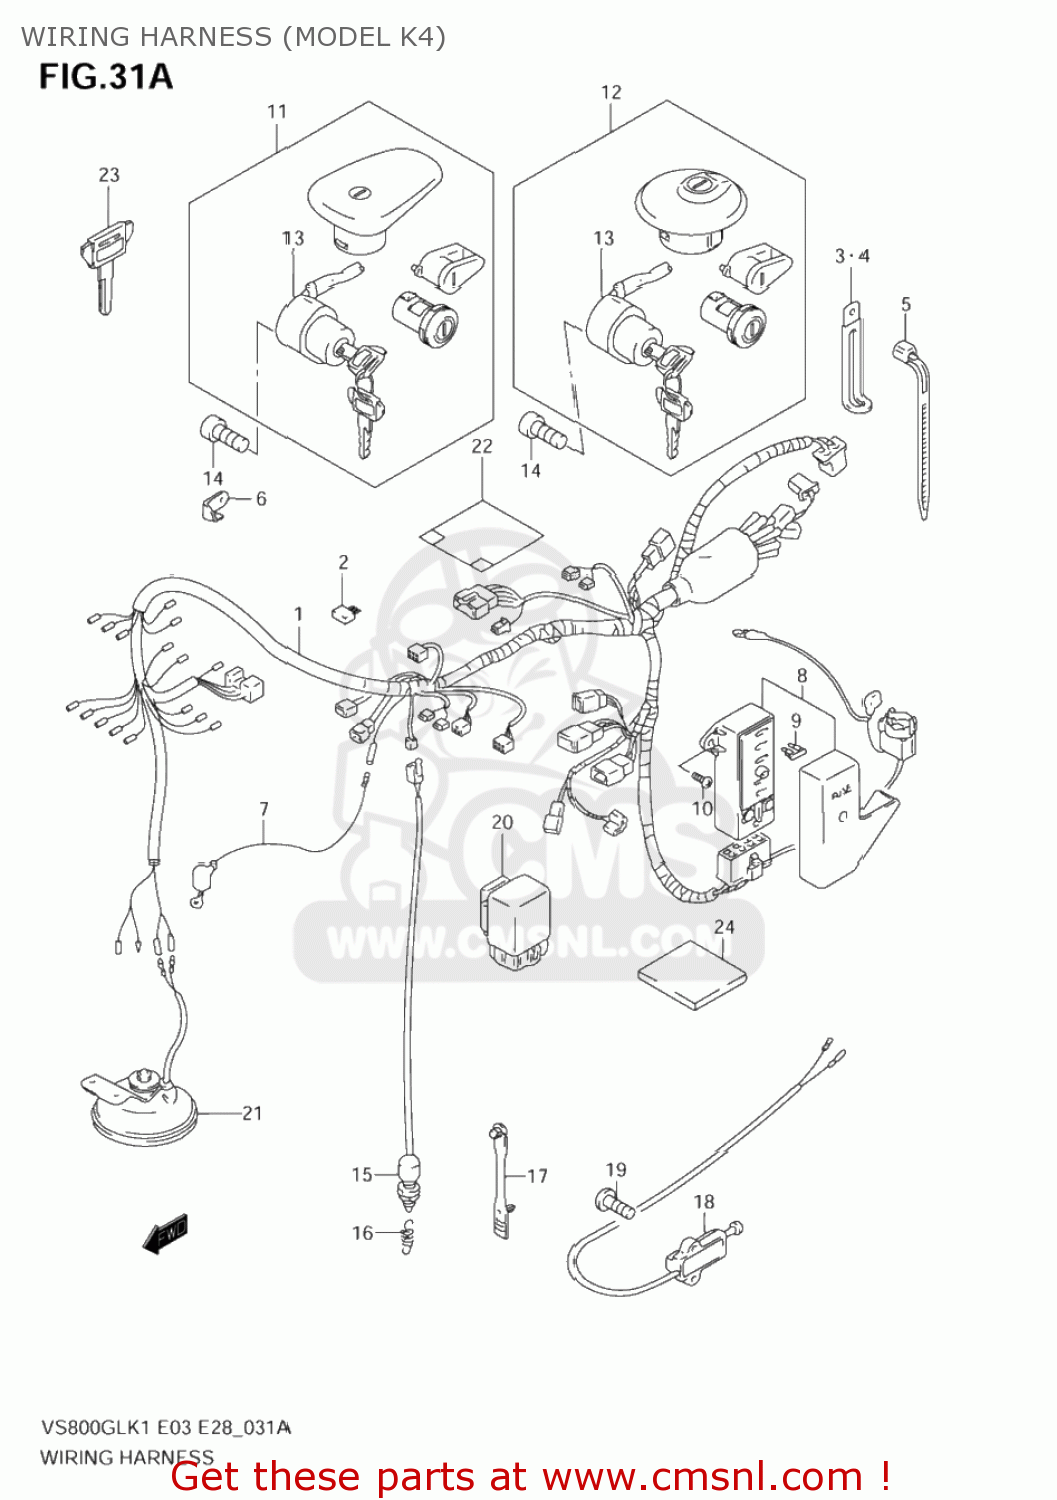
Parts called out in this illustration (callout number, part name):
1	HARNESS,WIRING
2	DIODE(STANLEY DE8804)
3	CLAMP(L:65)
4	CLAMP(L:45)
5	CLAMP(L:125)
6	PLATE,COUPLER HOLDER
7	WIRE,WATER TEMP GAUGE LEAD
8	BOX ASSY,FUSE
9	FUSE(10A)
10	SCREW
11	LOCK SET
12	LOCK SET
13	SWITCH ASSY,IGNITION
14	BOLT
15	SWITCH ASSY,STOP LAMP
16	SPRING
17	CLAMP,L:88
18	SWITCH ASSY,SIDE STAND
19	SCREW
20	RELAY ASSY
21	HORN ASSY
22	COVER,WIRING HARNESS
23	KEY,BLANK(TYPE:C)
24	COVER,HARNESS
